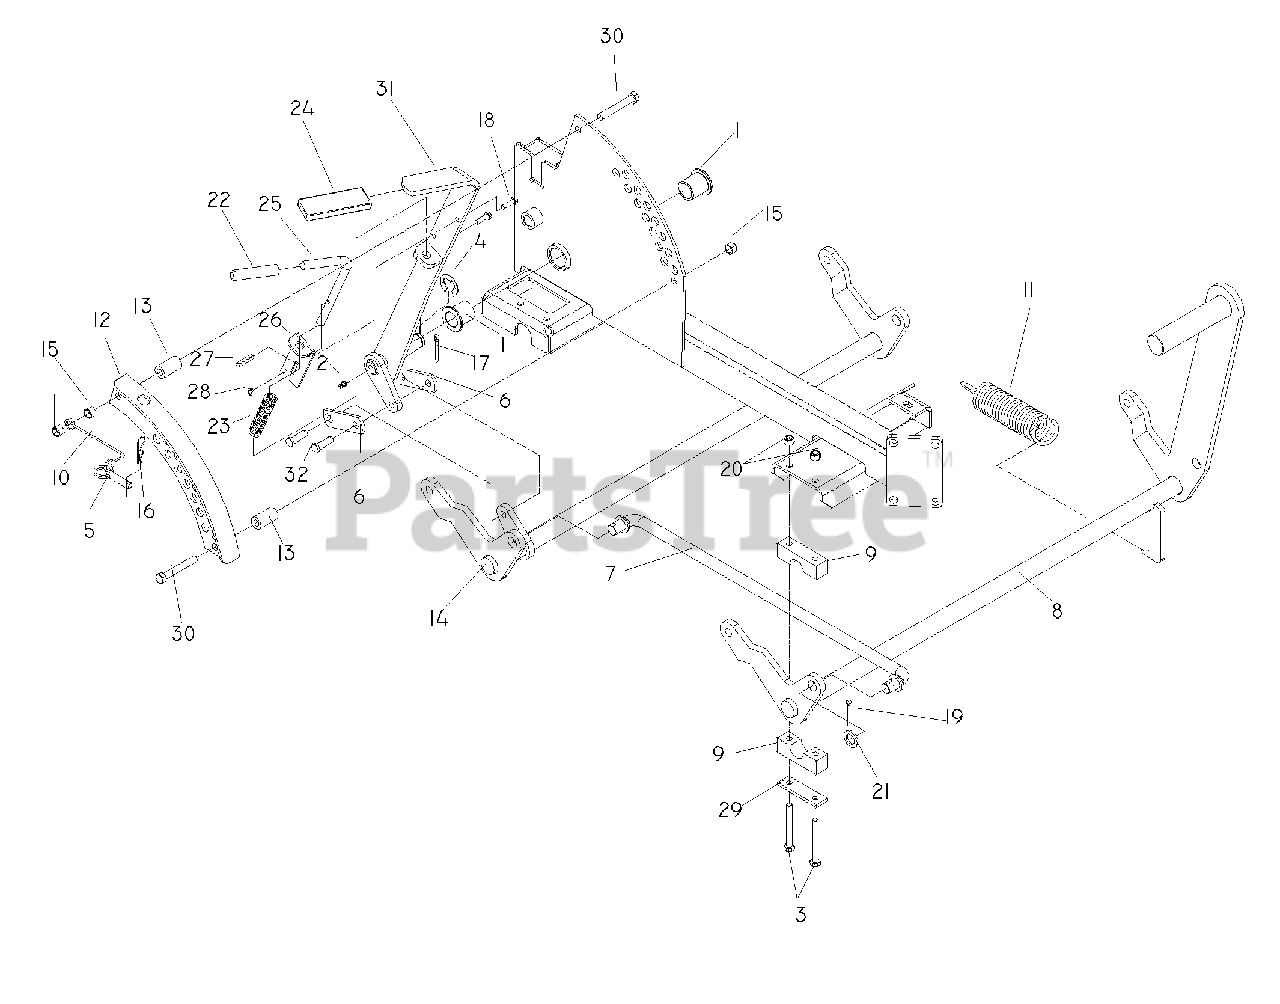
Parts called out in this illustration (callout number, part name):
1	BUSHING, FLANGED
3	HCS 5/16C X 2-3/4
4	E-RING 7/8
5	HITCH PIN
6	LIFT ARM
7	CROSS LINK
8	SHAFT, LIFT-FRONT
9	PILLOW BLOCK
10	LANYARD
12	ADJUSTMENT PLATE WLDMT
13	DECK LIFT SPACER
14	SHAFT, LIFT-REAR
15	NUT 3/8-16 NYLOC
16	HAIRPIN #4
17	COTTER PIN 1/8 X 3/4
18	HCS 1/4C X 3/4 HCS
19	COTTER PIN
20	NUT 5/16 NYLOC
21	BUSHING
26	PIN MT, UPPER
27	ROLL PIN
28	NUT 1/4C CENTER LOCK
29	REINFORCEMENT BAR
30	HCS 3/8C X 2 1/2
31	LIFT LEVER WELDMENT
32	CLEVIS PIN 3/8 X 1 1/8
